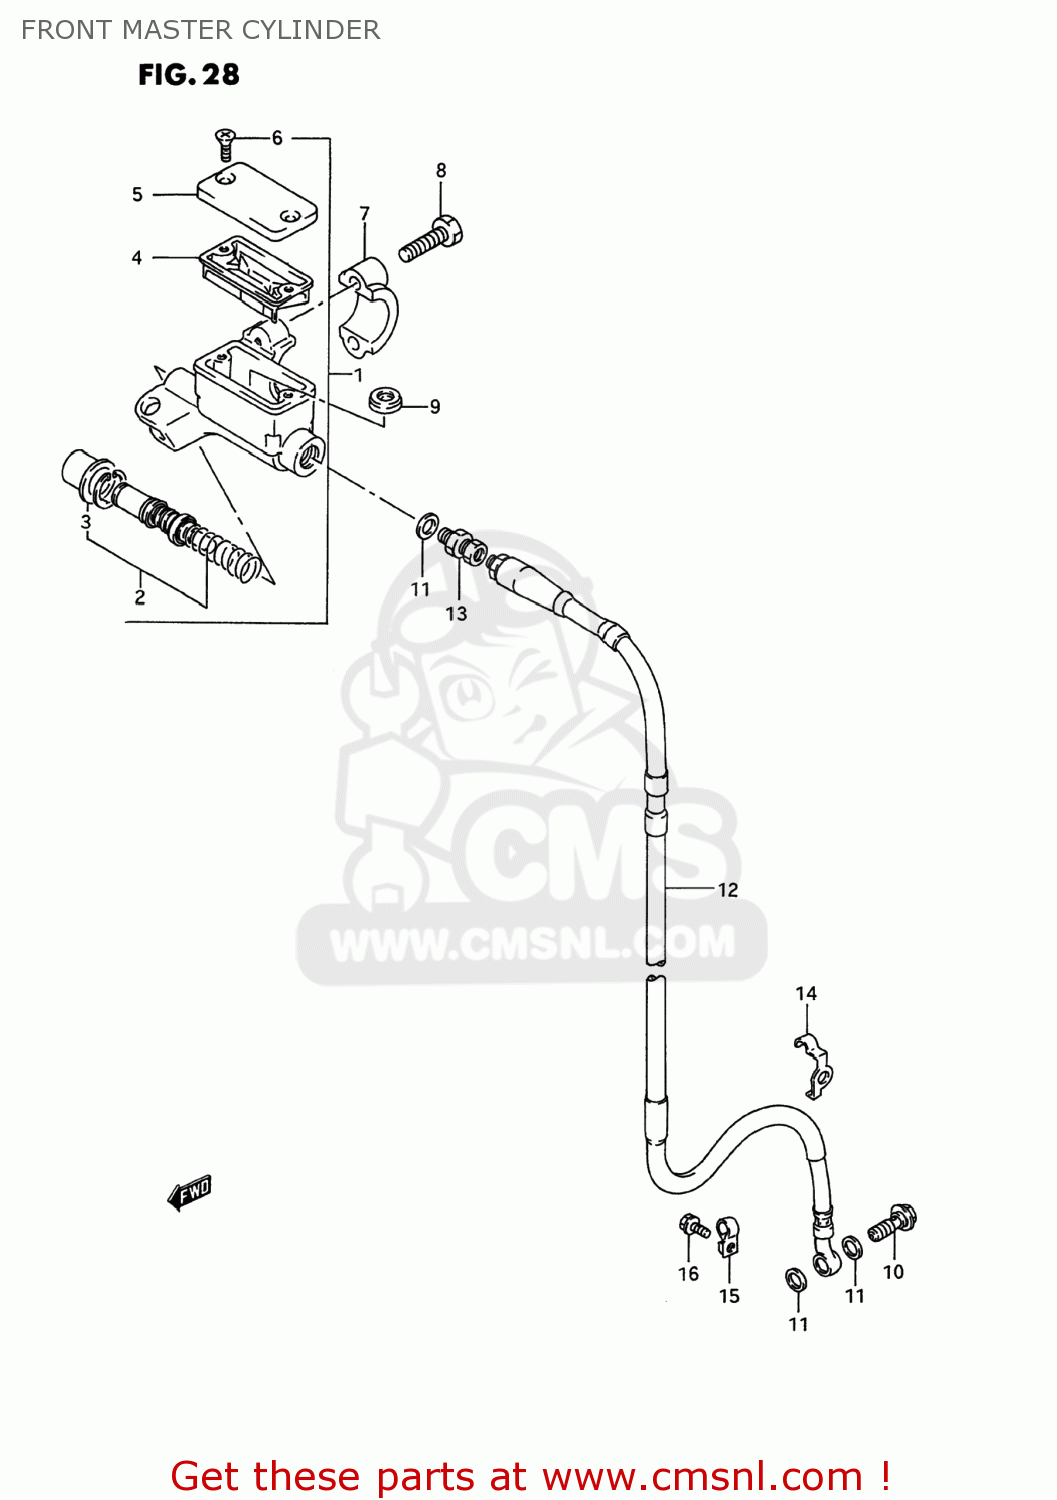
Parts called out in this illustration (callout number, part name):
1	CYLINDER ASSY,FR MASTER
2	PISTON & CUP SET
3	BOOT
4	DIAPHRAGM
5	CAP
6	SCREW
7	HOLDER
8	BOLT
9	SEPARATOR
10	BOLT UNION
11	WASHER(10X15X1.5)
12	HOSE,FR BRAKE
13	ADAPTOR,BRAKE HOSE
14	CLAMP,FRONT BRAKE HOSE
15	CLAMP,FR BRAKE HOSE NO.2
16	BOLT
